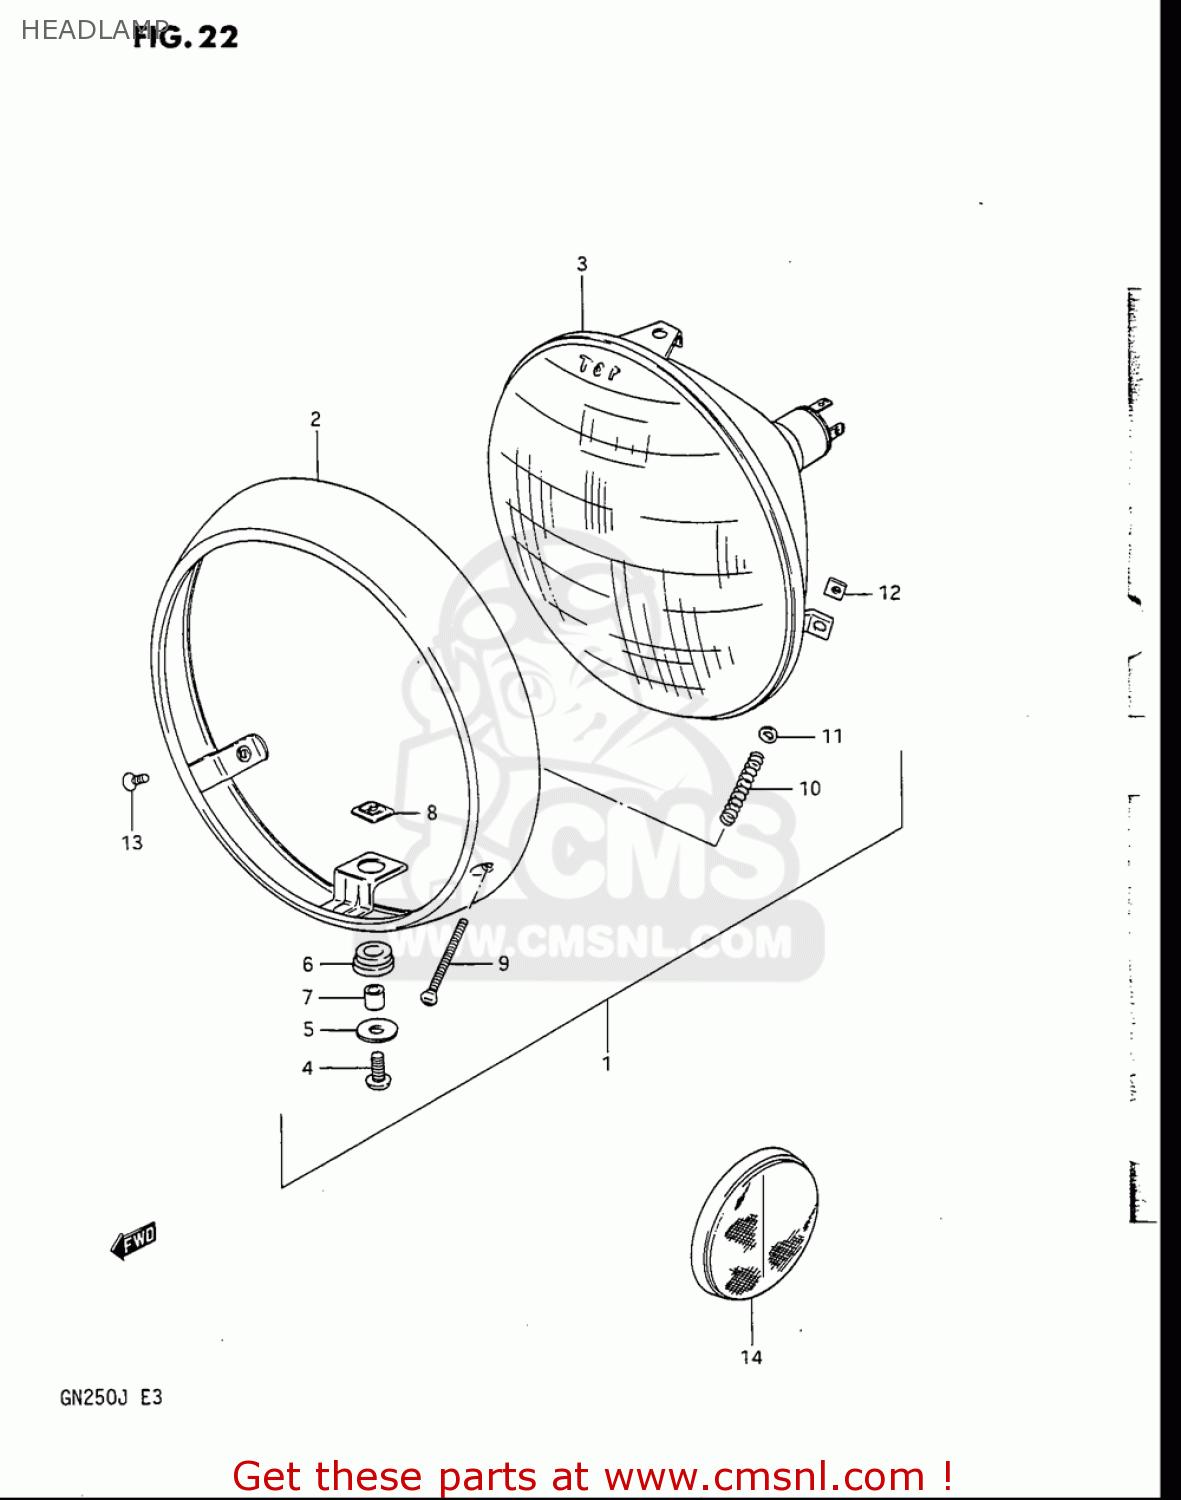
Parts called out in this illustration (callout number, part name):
1	LAMP ASSEMBLY,HEAD
2	RIM
3	LAMP UNIT
4	SCREW
5	WASHER(5.5X18X1)
6	CUSHION
7	SPACER
8	NUT
9	SCREW
10	SPRING
11	WASHER
12	NUT
13	SCREW(5X12)
14	REFLEX REFLECTOR,RR
